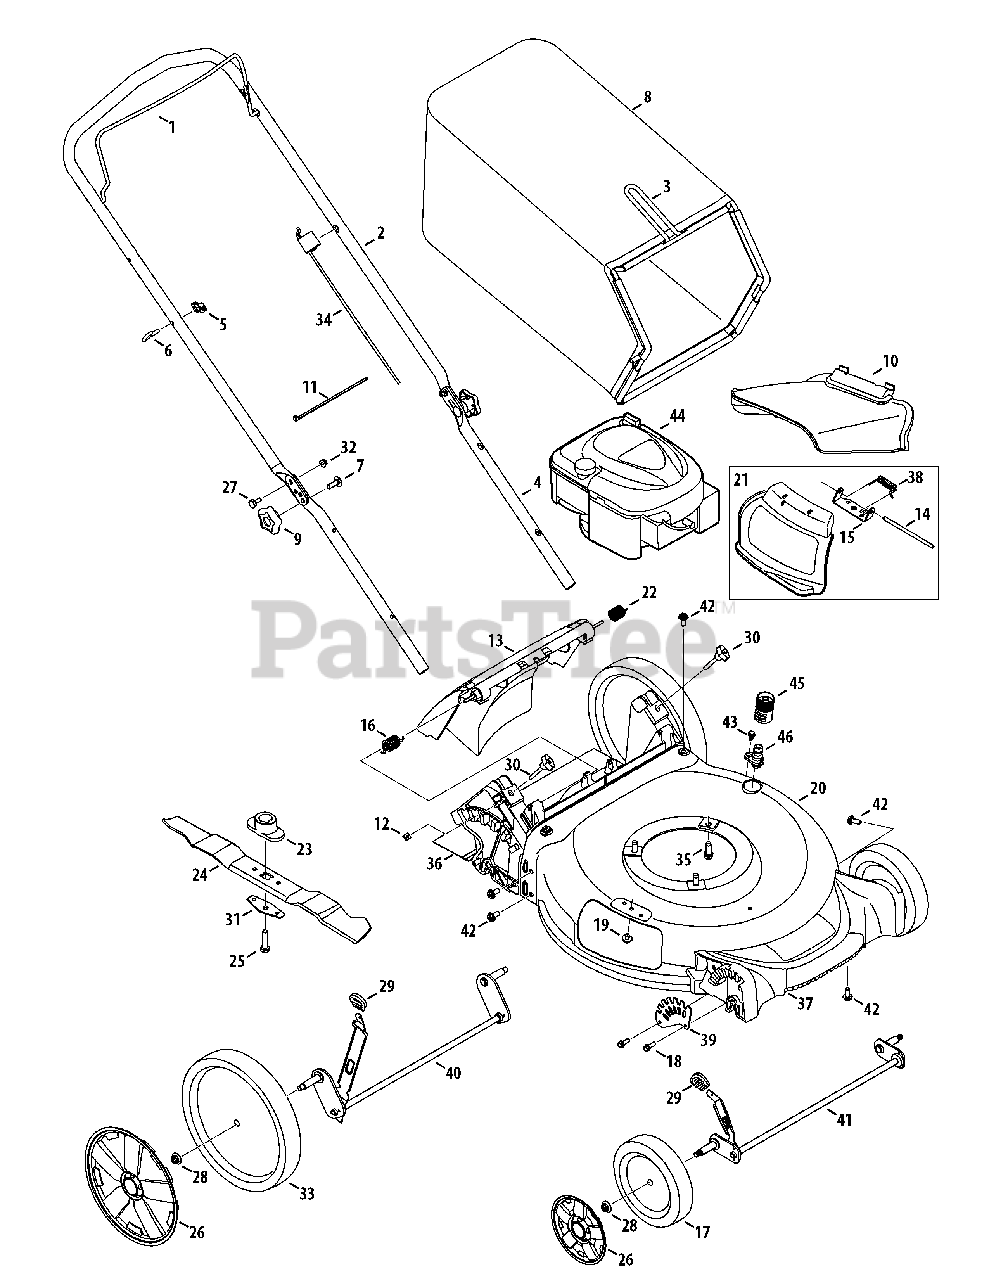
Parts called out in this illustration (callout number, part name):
1	Blade Control
2	Upper Handle
4	Lower Handle
5	Wing Nut
6	Rope Guide
7	Carriage Screw, 5/16-18
8	Grass Bag
9	Hand Knob
10	Side Chute
11	Cable Tie
12	Nut, Sq., 1/4-20
13	Rear Discharge Door Assembly
14	Hinge Pin
15	Chute Deflector Bracket
16	Torsion Spring - RH
17	Wheel, 7 x 2
18	Screw, 1/4-15 x .750
19	Screw, 1/4-20 x .500
20	Deck - 21"
21	Hinged Mulch Plug Assembly
22	Torsion Spring - LH
23	Blade Adapter
24	Mulching Blade
25	Screw , 3/8-24 x 1.50
26	Hub Cap - Front
26	Hub Cap - Rear
27	Sldr. Screw, .375 x .126 x 1/4-20
28	Flange Lock Nut, 3/8-16
29	Adjustment Lever Knob
30	Wing Nut
31	Blade Bell Support
32	Nut, Flange Lock, 1/4-20
33	Wheel, 11 x 2
34	Control Cable
35	TT Sems Screw, 3/8-16 x 1.0
36	Trail shield
37	Front Cover
38	Torsion Spring
39	Front Height Adjuster Plate
40	Rear Axle Assembly
41	Front Axle Assembly
42	Screw, 5/16-14 x .750
43	Screw, 1/4-20 x .500
44	Engine - 128M02-0952-F1
45	Water Nozzle Adapter
46	Deck Wash Nozzle
